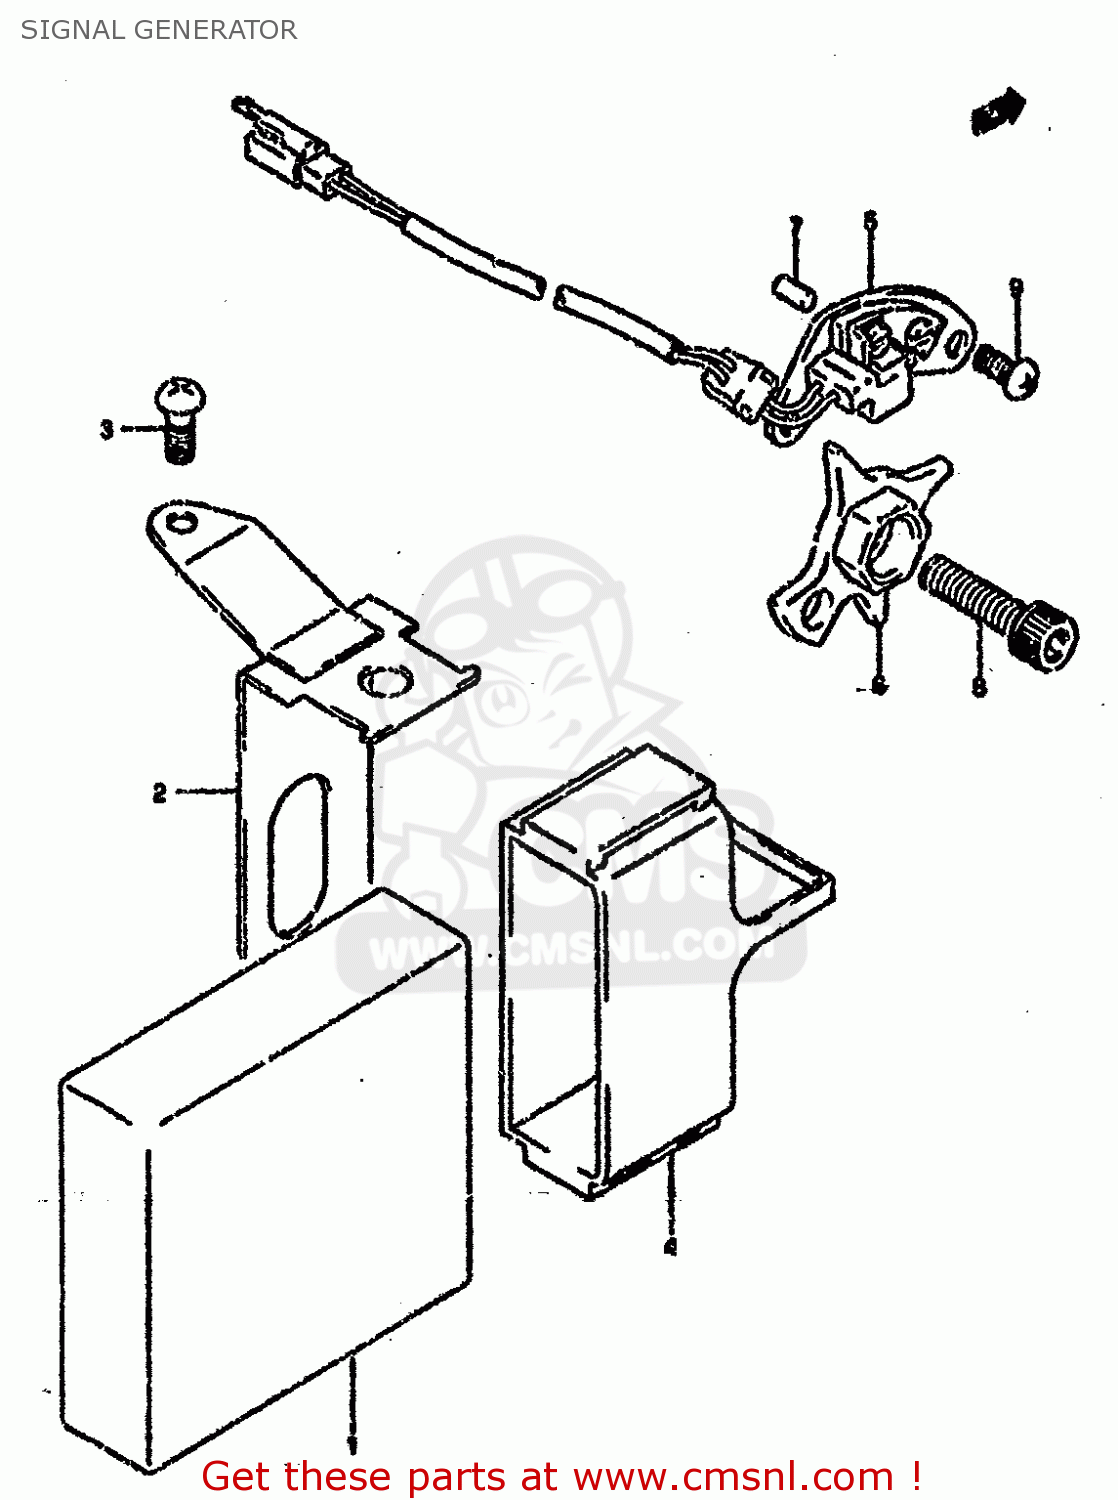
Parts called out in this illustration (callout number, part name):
1	IGNITER ASSY
2	BRACKET
3	SCREW
4	CUSHION
5	STARTER,SIGNAL GENERATOR
6	ROTOR,SIGNAL GENERATOR
7	PIN
8	BOLT
9	SCREW
